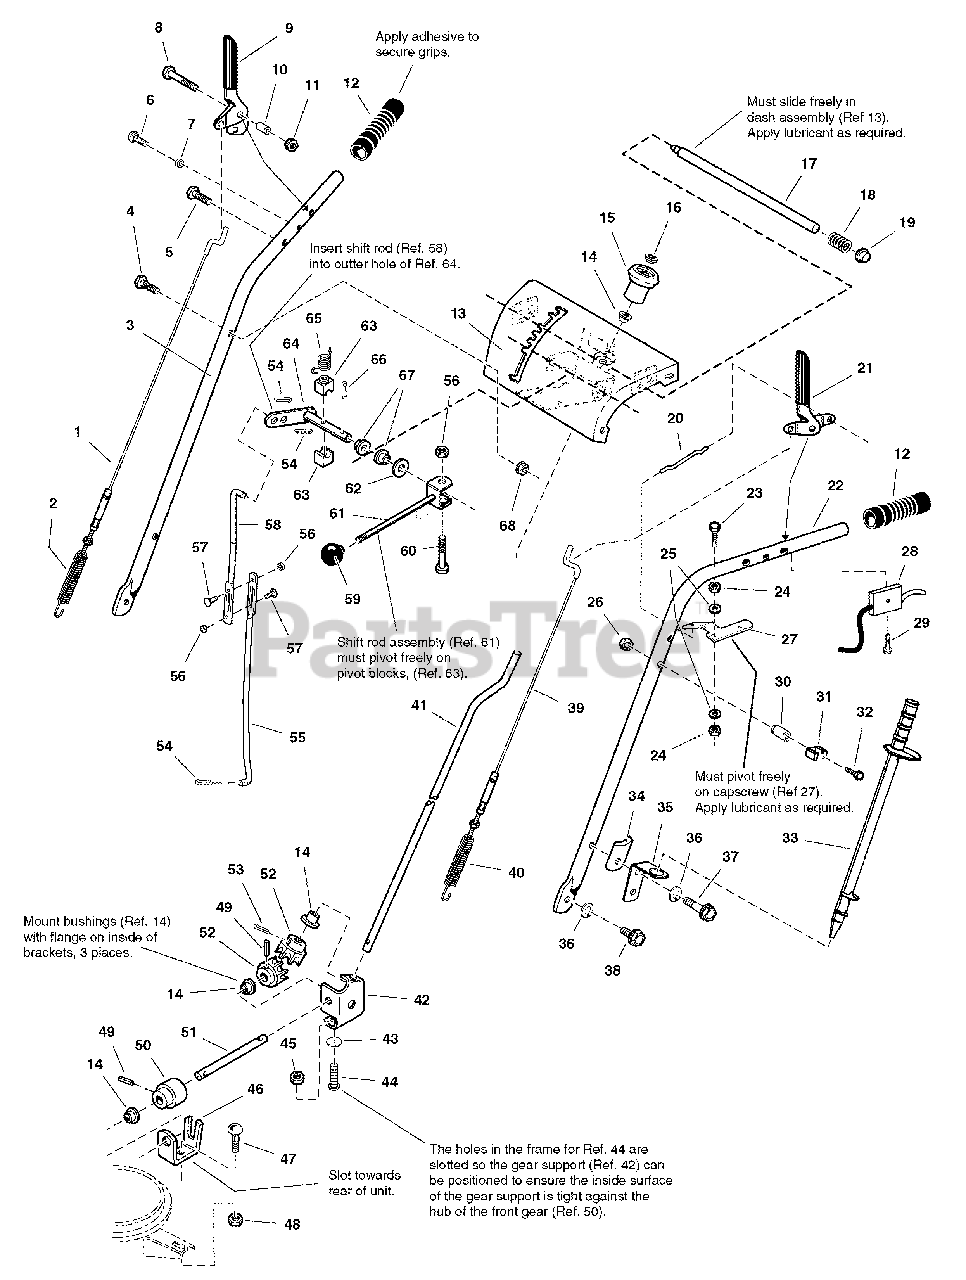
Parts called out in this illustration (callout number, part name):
1	CABLE AND SPRING ASSEMBLY, R.H. Auger
2	SPRING, Torsion
3	HANDLE, Tube, R.H.
4	CAPSCREW, Hex Head, 5/16-18 x 1-3/4 G5
5	CAPSCREW, Hex Head, 5/16-18 x 1-1/2 G5
6	SCREW, Pan Head Torx, 1/4-20 x 3/4, Thread Cutting
7	SPACER, 1/4ID x 25/64OD x 11/64LG
8	CAPSCREW, Hex Head, 1/4-20 x 1-1/2 G5
9	HANDLE, Clutch R.H.
11	NUT, Hex Centerlock, 1/4-20
13	DASH AND SUPPORT ASSEMBLY, Tubular
14	BUSHING, 47/125ID x 437/1000OD x 1/5LG
15	KNOB, Spinner
16	NUT, Push Pal, 3/8" Diameter Stud Capped
17	ROD AND SPRING ASSEMBLY, w/Pin
18	SPRING, Complete
19	PUSH NUT, Stud Cap, 1/2
20	ROD, 4/25" Diameter, E-Coat
21	HANDLE, Clutch L.H.
22	HANDLE, Tube, L.H.
23	CAPSCREW, Hex Head, 1/4-20 x 2 G5
24	NUT, Hex Lock ESNA Light, 1/4-20NC-3B
25	WASHER, 1/4
26	NUT, Hex Lock, 10-24
27	LEVER, Pivot
28	CABLE AND HANDLE ASSEMBLY, Clutch
29	SCREW, Pan Head Torx, #10 x 1/2 Thread Cut
30	SPACER, 1-1/4 LG Beveled End
31	CLIP, Snow Stick
32	SCREW, Hex Flange Slot, #10-24 x 2-1/2
33	STICK, Snow Removal
34	CLAMP, Saddle Snow Handle E-Coat
35	BRACKET, Clean Out Tool
36	LOCKWASHER, Spring, 5/16
37	CAPSCREW, Hex Head 5/16-18 x 2 G5
38	SCREW, Hex Whiz Lock Flange, 5/16-18 x 3/4
39	CABLE AND SPRING ASSEMBLY, L.H. Traction
40	SPRING, Extension
41	ROD, 3/8" Diameter, 26" Long
42	SUPPORT, Gear
43	NUT, Push for 1/4 Diameter Thread
44	CARRIAGE BOLT, 1/4-20 x 5/8 G5
45	NUT, Hex Flange, 1/4-20, Whiz Lock Small
46	SUPPORT, Worm
47	CARRIAGE BOLT, 5/16-18 x 3/4 G5
48	NUT, Hex Keps, 5/16-18, Conical Washer
49	PIN, Spring 1/8 x 3/4
50	WORM, Chute, L.H.
51	ROD, 3/8" Diameter, Chute Worm E-Coat
52	GEAR, Powdered Metal, Metafusion
53	PIN, Cotter 1/4 x 1
54	PIN, Quick
55	ROD, 3/4" Diameter
56	NUT, Hex KEPS, 1/4-20, Conical Washer
57	CARRIAGE BOLT, 1/4-20 x 3/4 G5
58	ROD, 3/4" Diameter, Shift Upper, 11-19/50 Long
59	KNOB, Intermediate Thread, 3/8-16
60	SCREW, Hex Whiz Lock Flange, 1/4-20 x 2-1/4
61	ROD AND CLEVIS ASSEMBLY, Shift, Threaded
62	WASHER, 1/2
63	BLOCK, Pivot, 3/4 x 3/4, Powdered Metal
64	ROD AND ARM ASSEMBLY, Pivot
65	SPRING, Torsion
66	CLIP, Hair Pin
67	BUSHING, 1/2ID x 3/4OD x 1/4LG
68	NUT, Hex Flange, 5/16-18 ESNA
